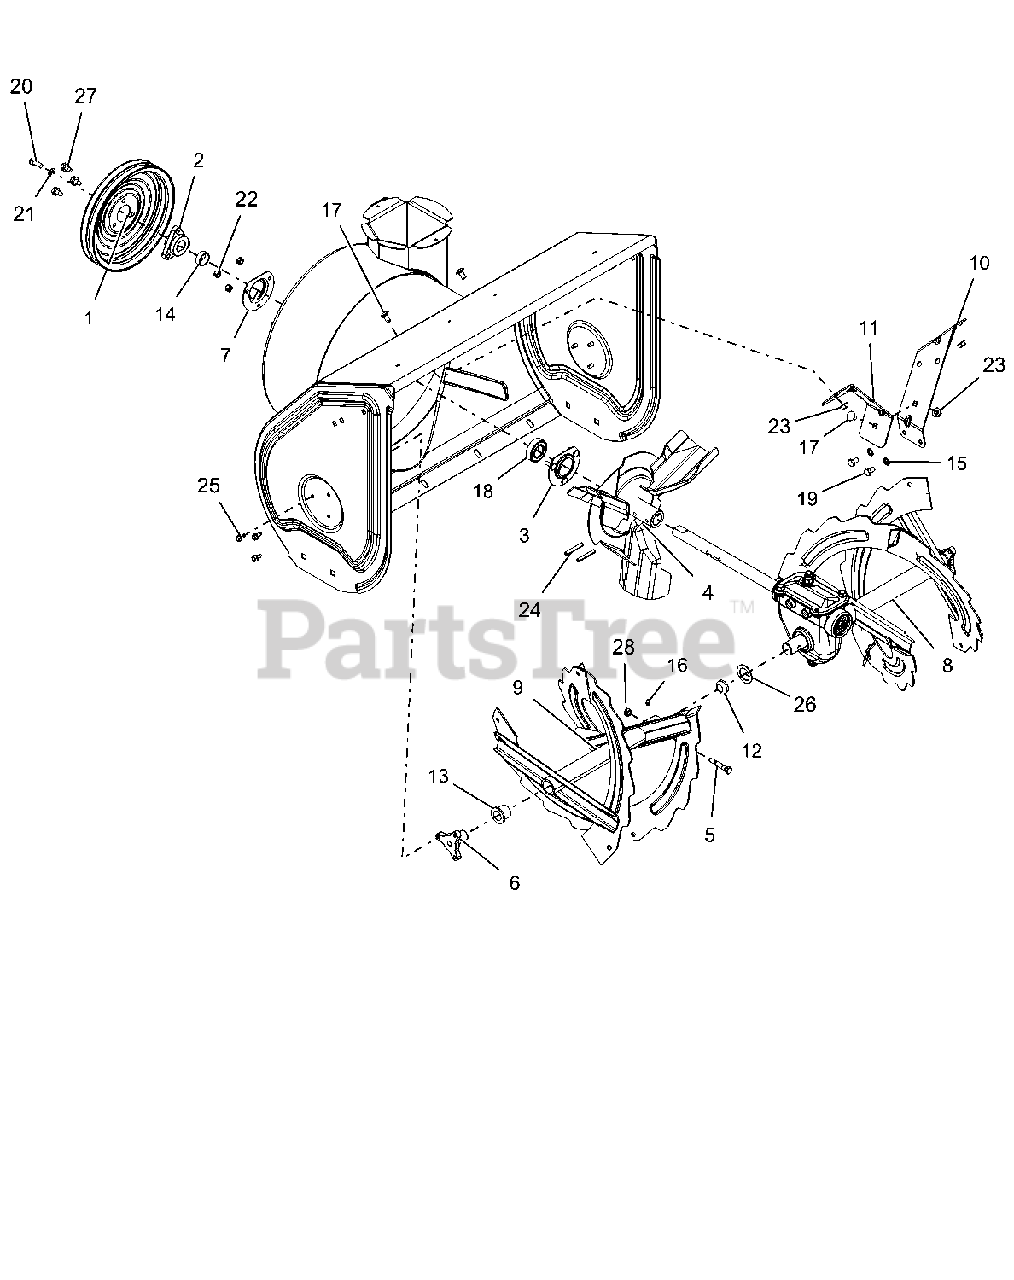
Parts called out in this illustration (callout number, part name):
1	PULLEY, SPIN FORM DUAL GROOVE
2	PULLEY HUB, D-BORE .87 DELUXE
3	BEARING FLANGE
4	IMPELLER, 3 BLADE-14"
5	SHEAR BOLT SERVICE ASSEMBLY
6	SUPPORT, RAKE BUSHING
7	BEARING FLANGE
8	RAKE, LEFT HAND-28" DELUXE
9	RAKE, RIGHT HAND-28" DELUXE
10	BRACKET, GEARCASE SUPPORT - LH
11	BRACKET, GEARCASE SUPPORT - RH
12	PLUG, RAKE TUBE
13	BSHG-FLG, NY.778 ID X 1.018 OD
14	BSHG-SPCR .895IDX1.065ODX.353
15	@WSHR-LK-EXT.326X.599X.031YWZC
16	ZERK,FITTING .25X.125 DRIVE IN
17	BLT-RDHDSQSHNK.31-18X.62 YZ-LK
18	BRG-BALL .876X1.75X.50 RSTFP
19	@BLT-HEX .31-18X.50 GR5 YWZC
20	BLT-HEX .31-24X.75 YWZC GR5
21	WSHR-LK .312X.097 HVY YWZC
22	@NUT-LK-CTR .25-20 YWZC
23	@NUT-LK-TOP-FLG .31-18 YWZC
24	PIN-ROLL .250X1.75
25	SCR-TAP .25-20X.50 HWH TR YWZ
26	WSHR-FL-STL 1.010X1.505X.062YZ
27	@SCR-TAP .31-18X.50 HWH TR YWZ
28	@NUT-LK-CTR .31-18 YWZC
